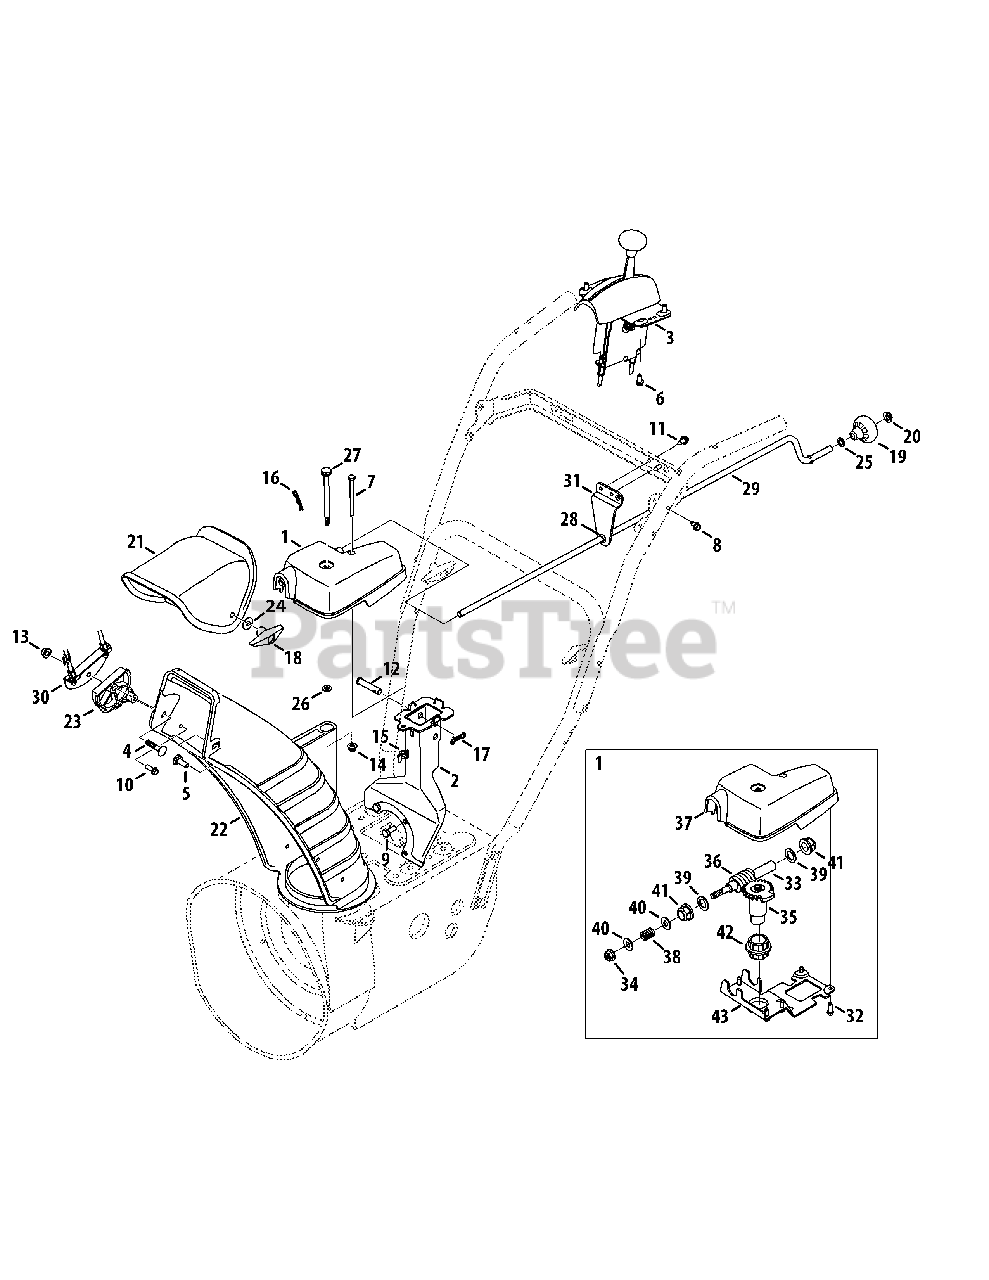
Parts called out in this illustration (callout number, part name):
1	Chute Rotation Gearbox
2	Chute Support Bracket
3	Chute Control, 2-Way
4	Bolt, Carriage, 5/16-18 x 1.50
5	Bolt, Carrier, 5/16-18 x 1.00
6	Screw, Hi-Lo, 1/4-15 x 0.50
7	Hex Head Screw, 1/4-20 x 3.00
8	Screw, TT, 1/4-20 x .500
9	Hex Head Screw, 5/16-24 x .750
10	Screw, Hi-Lo, 1/4-15 x 0.750
11	Screw, 1/4-20 x .625
12	Clevis Pin, 3/8 x 1.87
13	Nut, Flange Lock, 5/16-18
14	Nut, Flange Lock, 1/4-20
15	Wing Nut, 1/4-20
16	Internal Cotter Pin
17	Bow-Tie Cotter Pin
18	Wing Knob, 5/16-18
19	Shift Knob, .390
20	Push Cap, 3/8
21	Upper Chute
22	Lower Chute, 5.0
23	Cable Guide, Chute Tilt
24	Washer, Flat, .349 x .879
25	Flat Washer, .375 x .738 x .063
26	Washer, Flat, .25 x .630
27	Shoulder Screw, .312 x 3.5 x 1/4-20
28	Plastic Bushing, .380 ID
29	Chute Crank
30	Cable Bracket
31	Support Rod Bracket
32	Screw, 12-16 x .75
33	Worm Shaft
34	Flange Lock Nut, 3/8-16
35	Gear Assembly
36	Worm
37	Gear Cover
38	Compression Spring, .39 x .60 x .88
39	Flat Washer, .625 x 1.0 x .067
40	Flat Washer, .380 x .93 x .110
41	Hex Bearing
42	Flange Bearing
43	Gear Bracket
